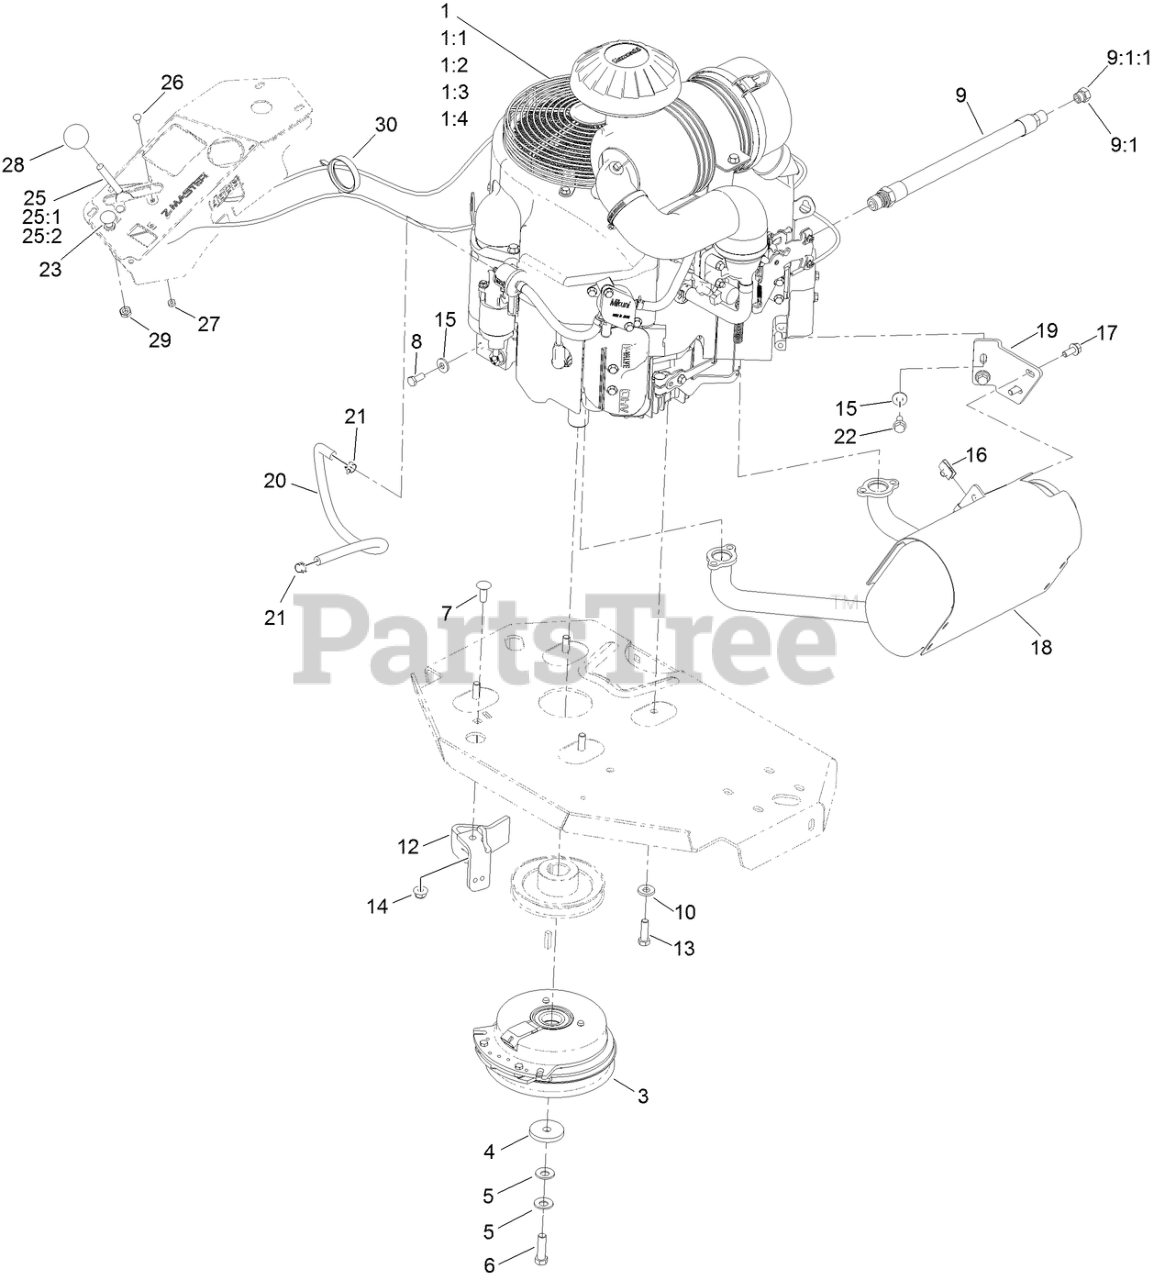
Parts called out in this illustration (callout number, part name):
1:1	KAWASAKI 49065-2078 ENGINE OIL FILTER
1:2	KAWASAKI 49019-0031 FUEL FILTER
1:3	KAWASAKI 11013-7039 SAFETY FILTER
1:4	KAWASAKI 11013-7038 AIR FILTER
3	CLUTCH KIT
4	WASHER-CLUTCH
5	WASHER-SPRING
6	SCREW-HH, W/LOCTITE
7	SCREW-CARR
8	SCREW-HH
9	ENGINE OIL DRAIN HOSE ASM
9:1	PLUG-HH
9:1:1	O-RING
10	WASHER-BELLEVILLE
12	CLUTCH-ANCHOR
13	SCREW-HH
14	NUT-HF, NI
15	WASHER-SPRING
16	NUT-U
17	SCREW-HHF
18	MUFFLER
19	BRACKET-MUFFLER
20	HOSE-FUEL
21	CLAMP-HOSE
22	SCREW-HHF
23	CONTROL-CHOKE
25	THROTTLE CONTROL ASM
25:1	LEVER-THROTTLE
26	BOLT-CARR
27	NUT-LOCK, NI
28	KNOB-BALL
29	NUT-HJ
30	CLAMP-HARNESS
